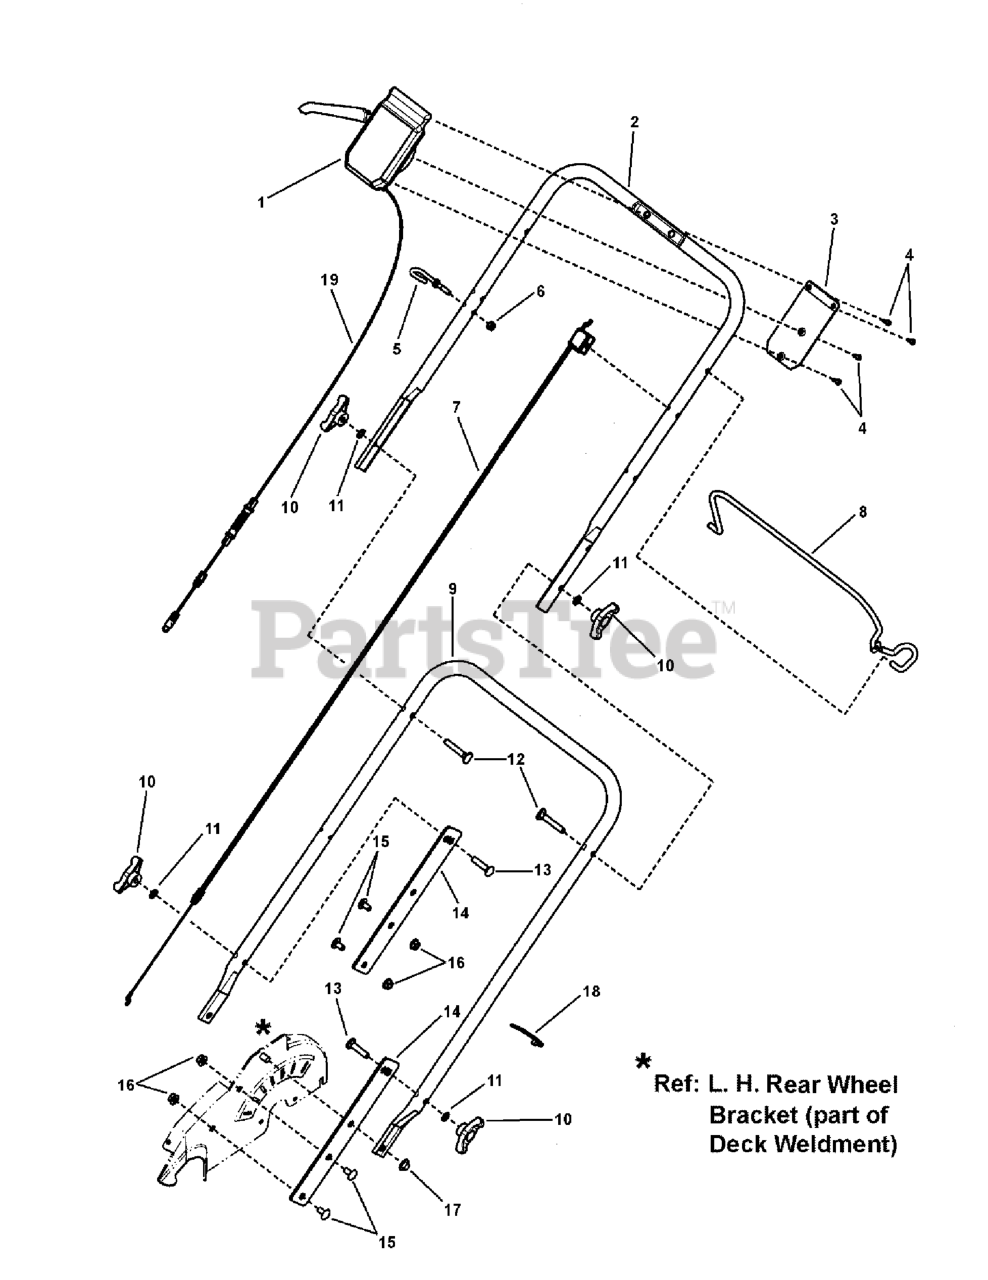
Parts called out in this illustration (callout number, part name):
1	ASSY, Control Head, Varaible Speed
2	HANDLE, Upper, Flat
3	PLATE, Control Panel
4	SCREW, #8-16 Torxplus Recessed Pan Head, Twin Helix
5	GUIDE, Rope (1/4-20 thread)
6	NUT, 1/4-20 Hex Nyloc
7	CABLE, Zone Control
8	BAIL, Operator Presence Control
9	HANDLE, Lower
10	KNOB, 5/16-18 Wing (Black)
11	WASHER, 5/16" Internal Tooth lock
12	BOLT, 5/16-18 x 2" Curved Head Square Neck, GR 2
13	BOLT, 5/16-18 x 1-1/2" Round Head Square Neck, YZ
14	BRACKET, Lower Handle
15	BOLT, 5/16-18 x 5/8" Round Head Short Square Neck, GR 5
16	NUT, 5/16-18 Flange Lock, YZ
17	PUSHNUT, 3/8
18	WIRE TIE, 11 Inch Std Black Nylon
19	CABLE, DRIVE
